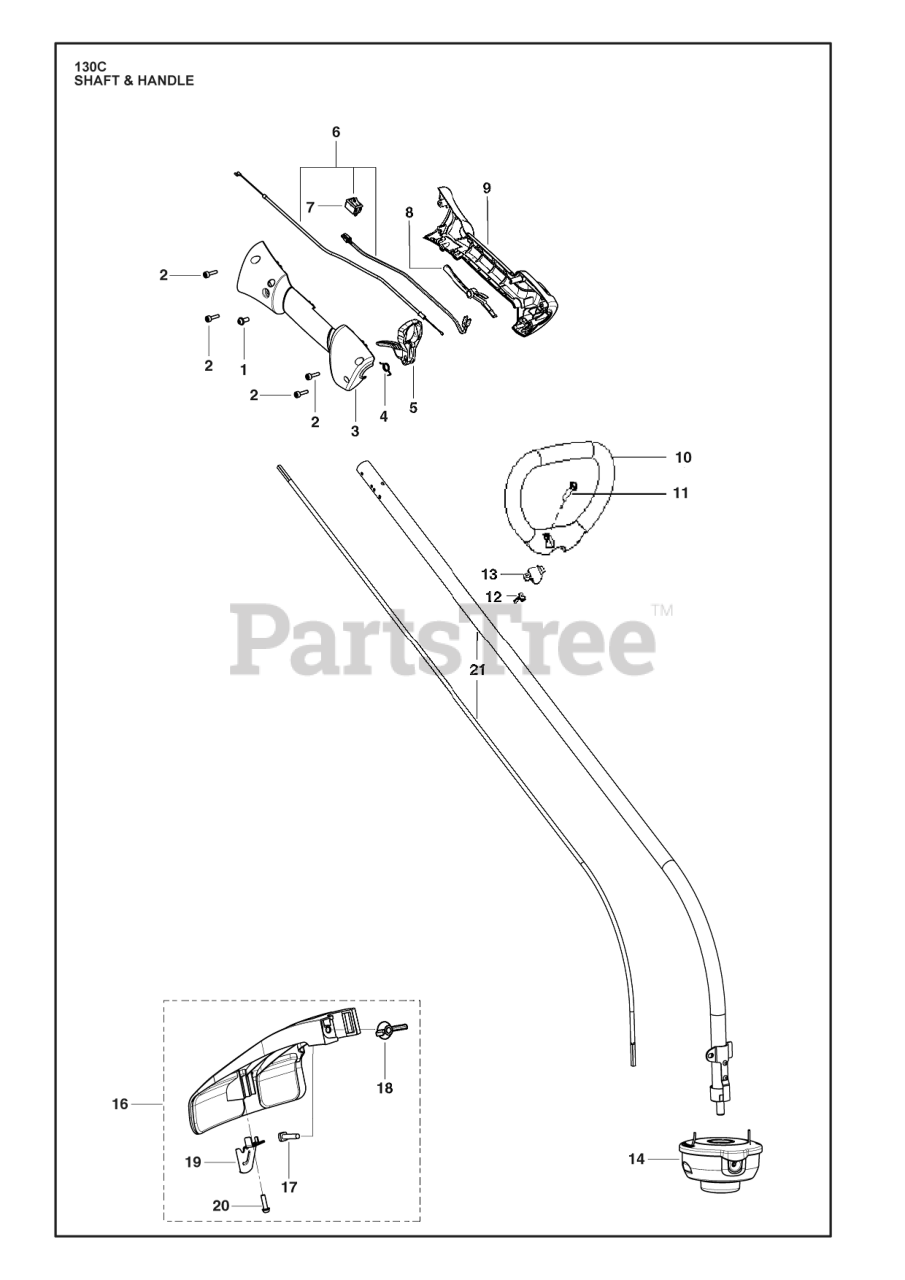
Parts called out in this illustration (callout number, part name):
1	SCREW
2	SCREW
3	HOUSING THROTTLE
4	SPRING TRIGGER
5	TRIGGER THROTTLE HVA ORANGE
6	ASSY CABLE / WIRE HARNESS
7	SWITCH
8	THROTTLE LOCKOUT HVA ORANGE
9	HOUSING THROTTLE
10	HANDLE, LOOP
11	SCREW
12	WING NUT
13	CLAMP
14	Trimmer Heads
16	SERVICE KIT 130C TRIMMER GUAR
17	BOLT, TYPE 2
18	WINGNUT, TYPE 2
19	CUTTER
20	SCREW
21	TUBE
